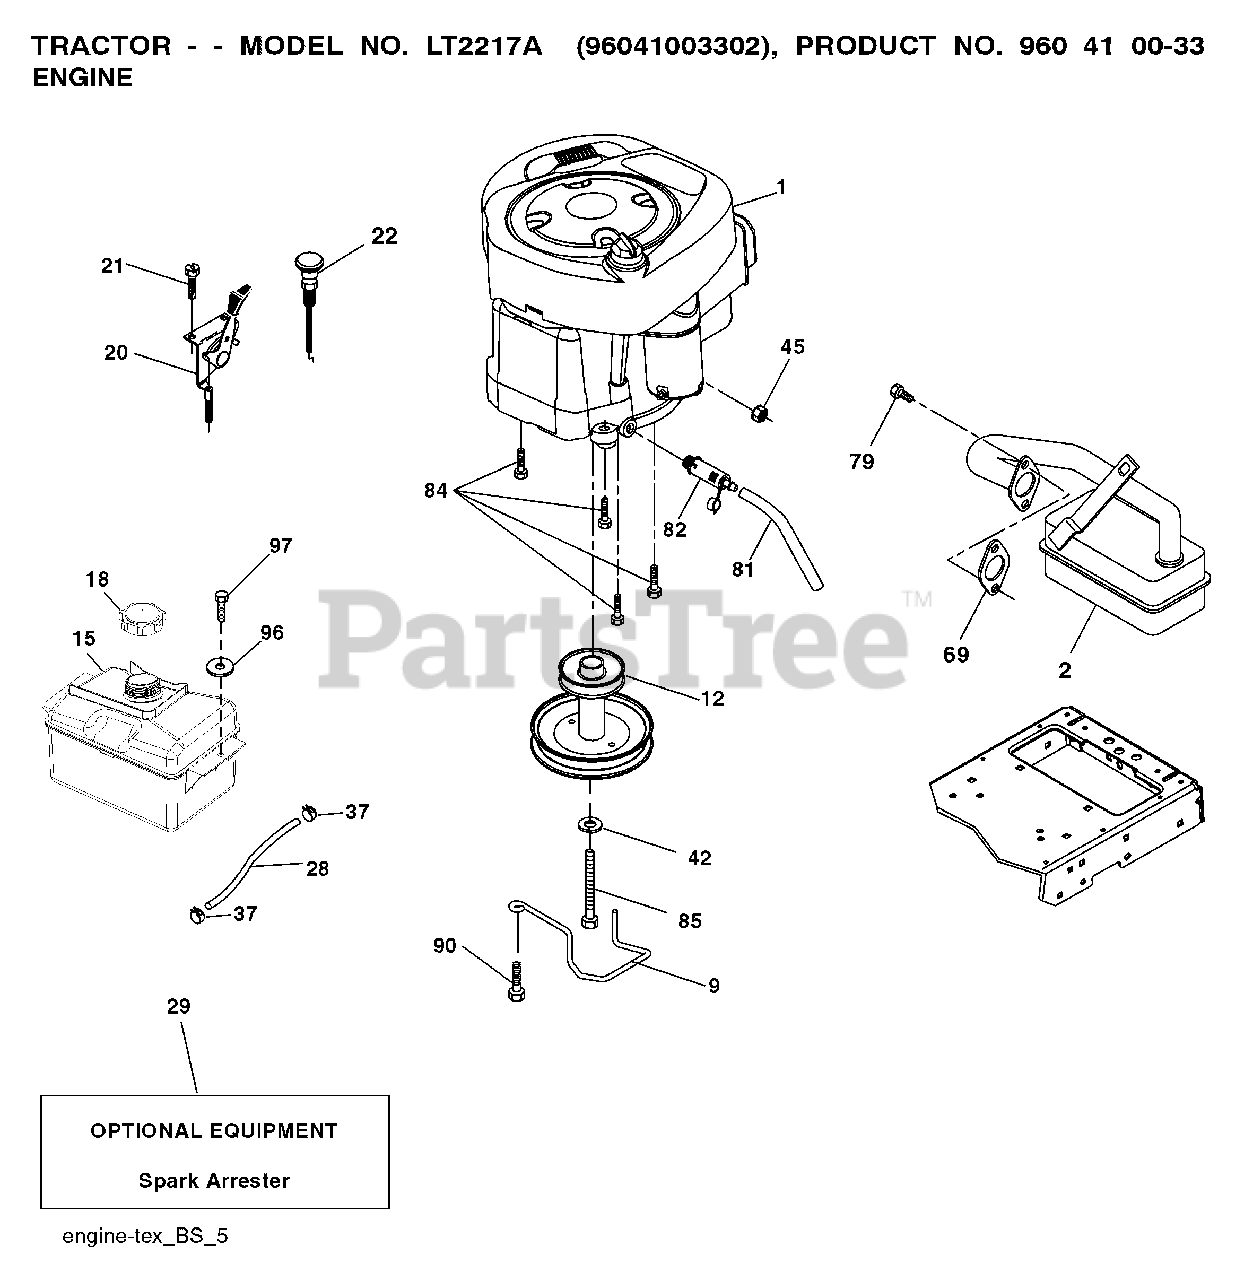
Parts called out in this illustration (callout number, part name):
9	KEEPER.BELT.ENGINE.3.25
12	PULLEY ENGINE
15	TANK FUEL FRT 1.5 GAL
18	FUEL CAP
20	CONTROL.TH/CK.C.
21	SCREW
28	LINE.FUEL.20
29	ARRESTER SPARK (OPTIONAL)
37	HOSE CLAMP
42	LOCKWASHER
45	NUT
69	REPL BY 532 27 22-93
79	SCREW.SOCKET HD.5/16-1
81	TUBE, DRAIN OIL ASM.
82	PLUG DRAIN OIL EASY
84	SCREW.3/8-16
85	BOLT HEX 7/16-20X4-1/4"
90	SCREW 3/8-16X1
97	SCREW HEXWSHR 1/4-20X3/4
102	SCREW
107	SCREW.1/4-20X5/8
